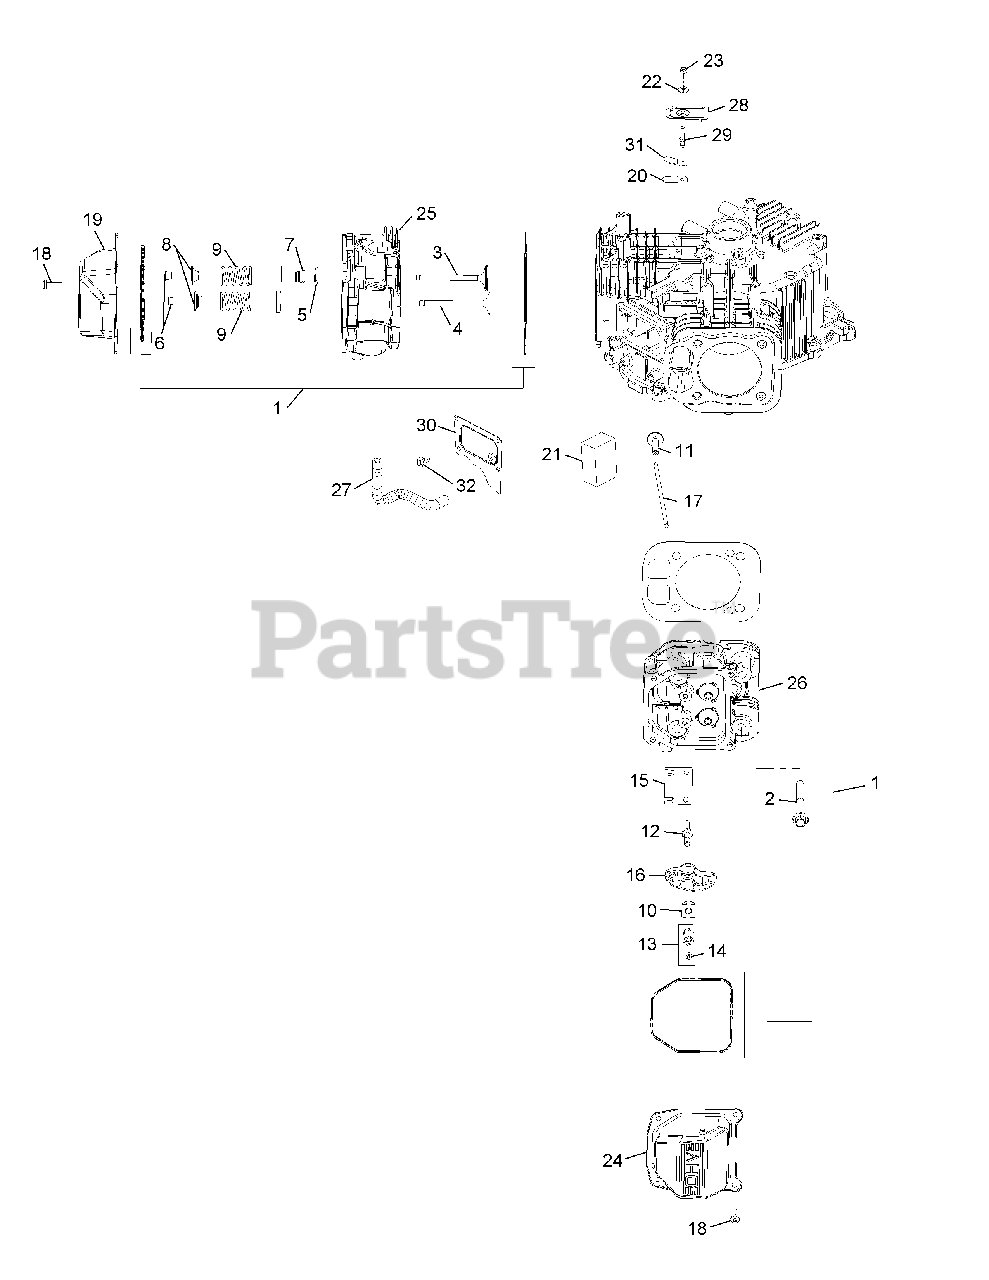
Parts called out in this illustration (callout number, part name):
1	Cylinder Head Gasket Kit
2	Flange Screw, M10 x 1.5 x 90
4	Exhaust Valve
5	Spacer (.010")
6	Retainer Kit
7	Valve Band Seal
8	Valve Spring Cap
9	Valve Spring
10	Rocker Arm Pivot
13	Hex Nut Assembly (Inc. #14)
18	Pan Head Screw
20	Breather Reed
21	Breather Filter
22	Sealing Washer
23	Lock Nut, M5 x 8
24	Rocker Cover
25	Cylinder Head Assembly Kit, #1
26	Cylinder Head Assembly Kit, #2
27	Breather Hose
28	Breather Cover
30	Breather Media Cover
31	Reed Retainer
32	Thread Forming Screw
